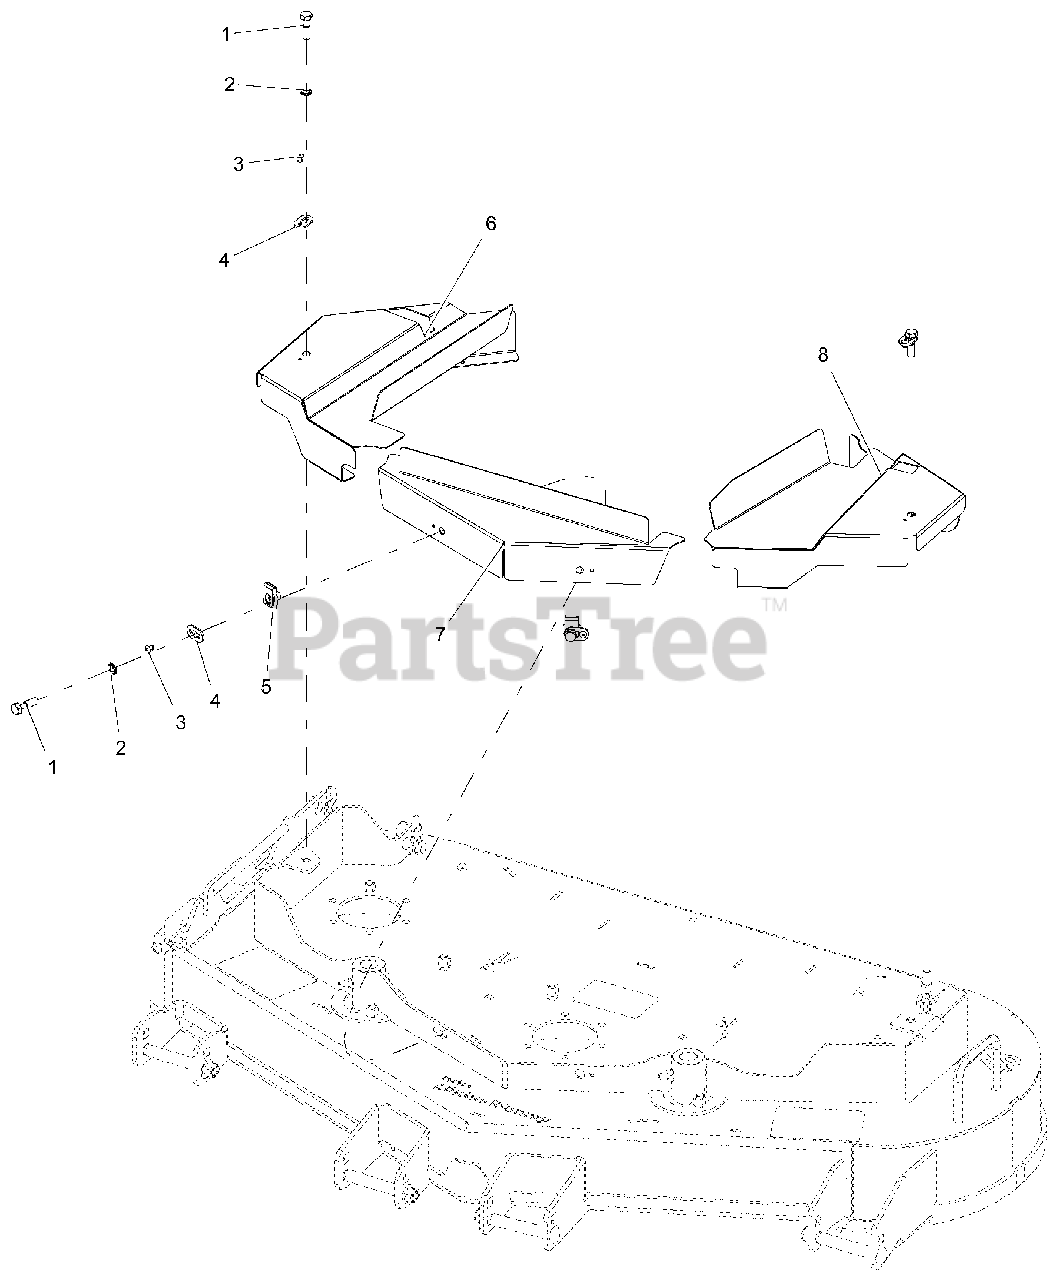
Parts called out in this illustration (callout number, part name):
1	BLT, HEX 0.38-16 X 1.25 GR5 CAPTIVE
2	LOCK, WSHR-EXT 0.391 X 0.628 X 0.036 YWZC
3	RVT-POP .187x.250 (#64) YWZC
4	KEEPER, BOLT
5	NUT, RTNR .375-16X.37
6	GUARD, BELT 48" RH (CE)-RED
7	GUARD, BELT 48" CE FRONT
8	GUARD, BELT 48" LH (CE)-RED
